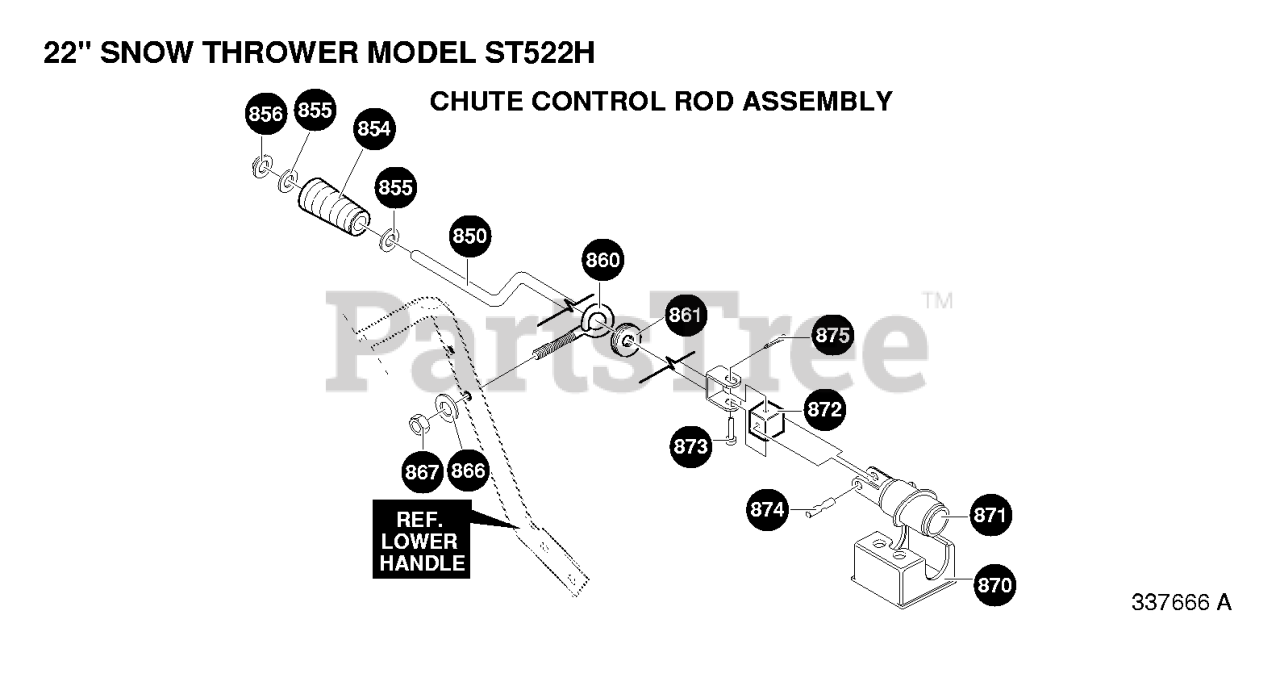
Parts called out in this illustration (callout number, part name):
850	CRANK ASSY W/YOKE
854	HANDLE, CHUTE CRANK
855	WASHER, FLAT .439 X .70 X .05
856	RETAINING RING
866	WASHER, FLAT .406X .81X.
867	NUT, 3/8-16 HEXNYL
870	BRACKET, WORM MOUNTING
871	WORM GEAR CHUTE ROTATE 585196
872	BLOCK, UNIV
873	PIN, CLEVIS
874	PIN, UNIV JOINT
875	COTTER PIN .06X.50
